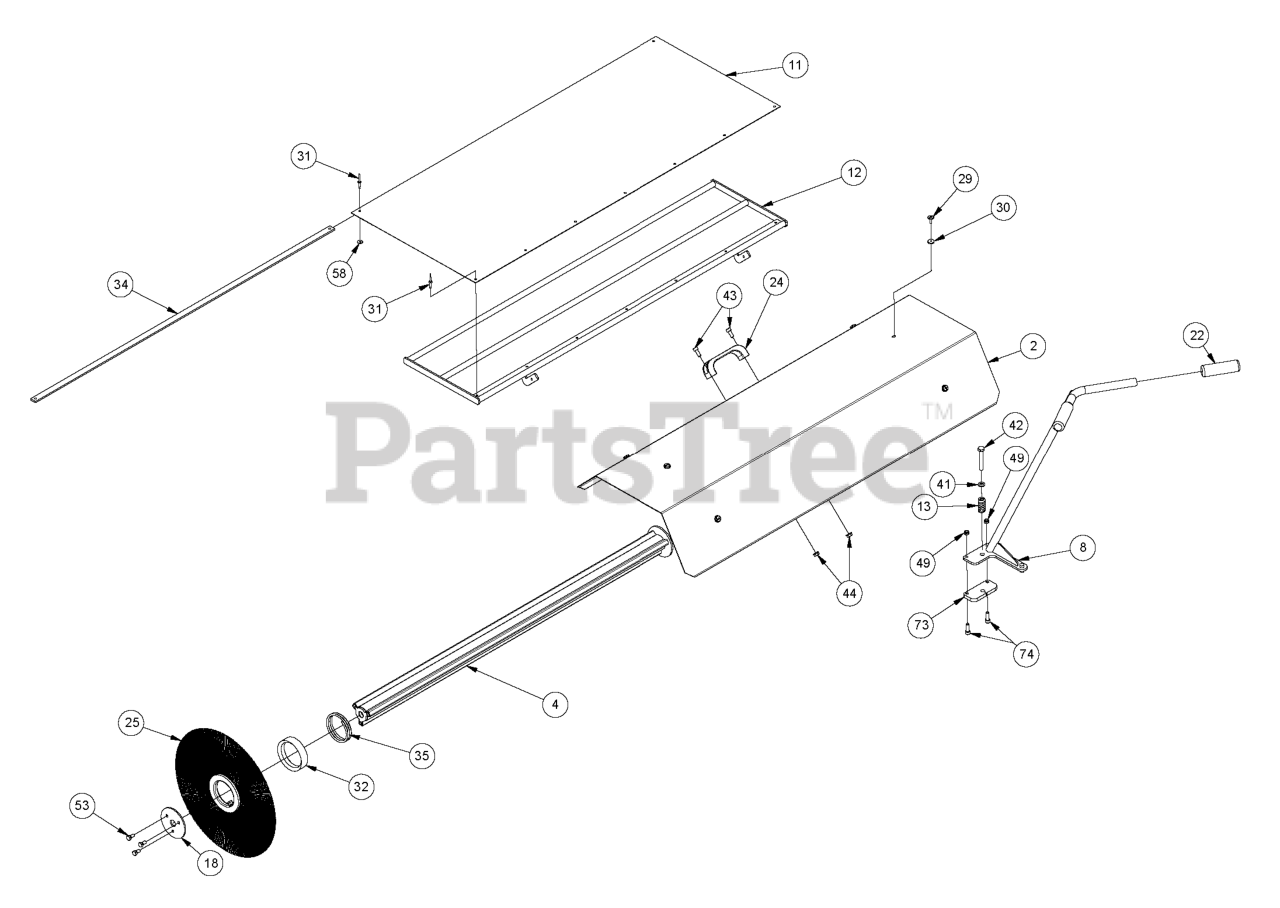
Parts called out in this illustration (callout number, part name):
11	PROTECTION
29	SCREW
32	SPACER
43	SOCKET
44	NUT LOCKING
49	NUT
